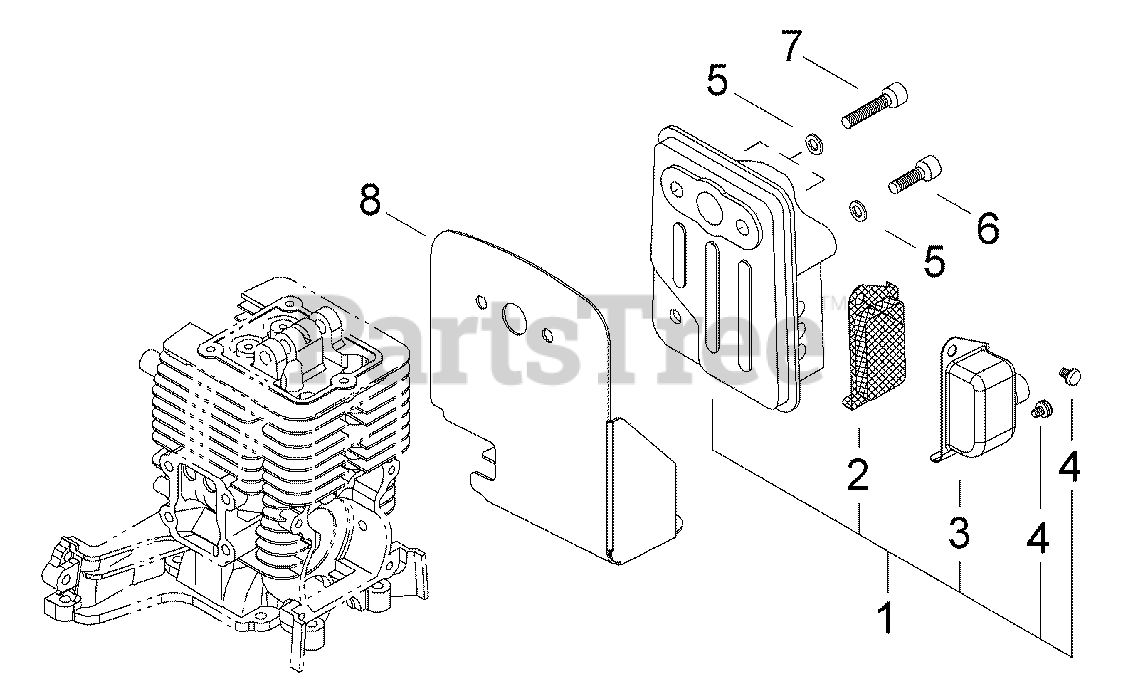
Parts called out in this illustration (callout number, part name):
1	MUFFLER ASSY
2	SCREEN, SPARK ARRESTER
3	GUIDE, EXHAUST
4	SCREW M4×6
5	WASHER, FLAT 5.5×10×0.8
6	BOLT 5×16
7	BOLT M5×25
8	HEAT SHIELD, EXHAUST
